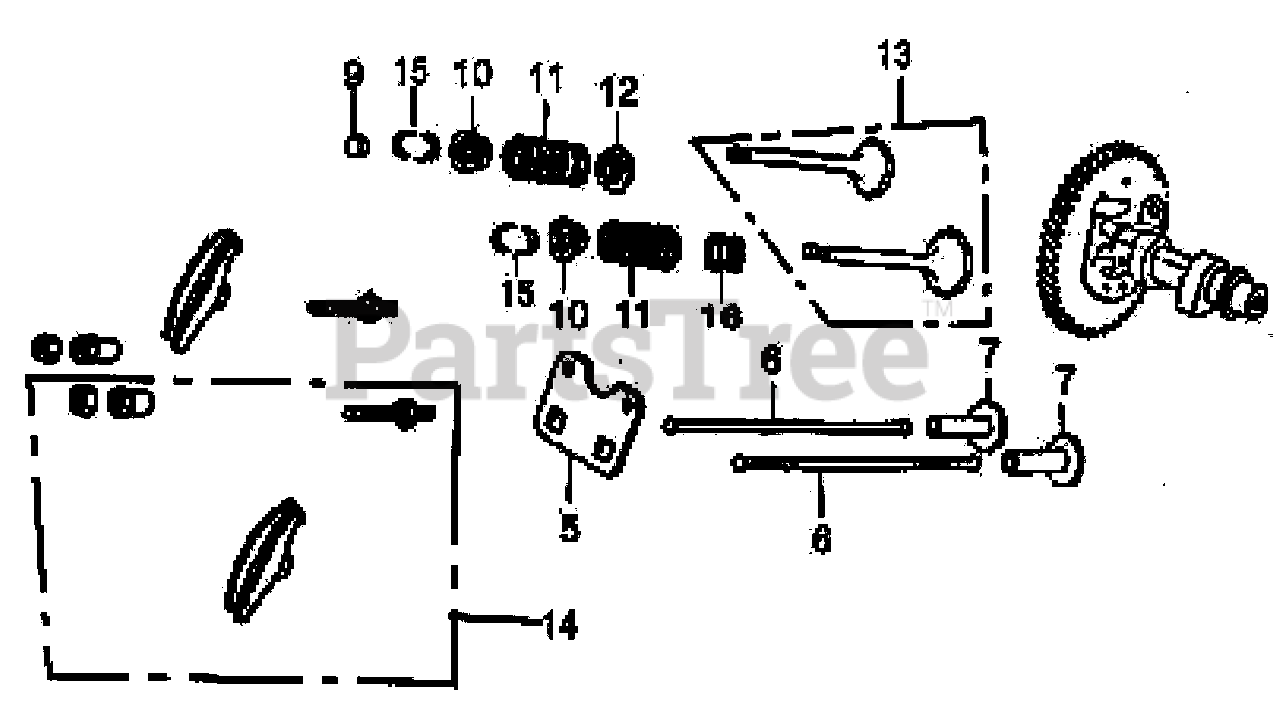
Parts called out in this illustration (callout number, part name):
5	PLATE, PUSHROD GUIDE
6	ROD, PUSH
7	LIFTER, VALVE
9	ROTATOR, VALVE
10	RETAINER, VALVE SPRING
11	SPRING, VALVE
12	SEAT, VALVE SPRING
13	VALVE ASSY.
14	ROCKER ARM ASSY..
15	LOCKER, VALVE
16	SEAL, VALVE STEM
